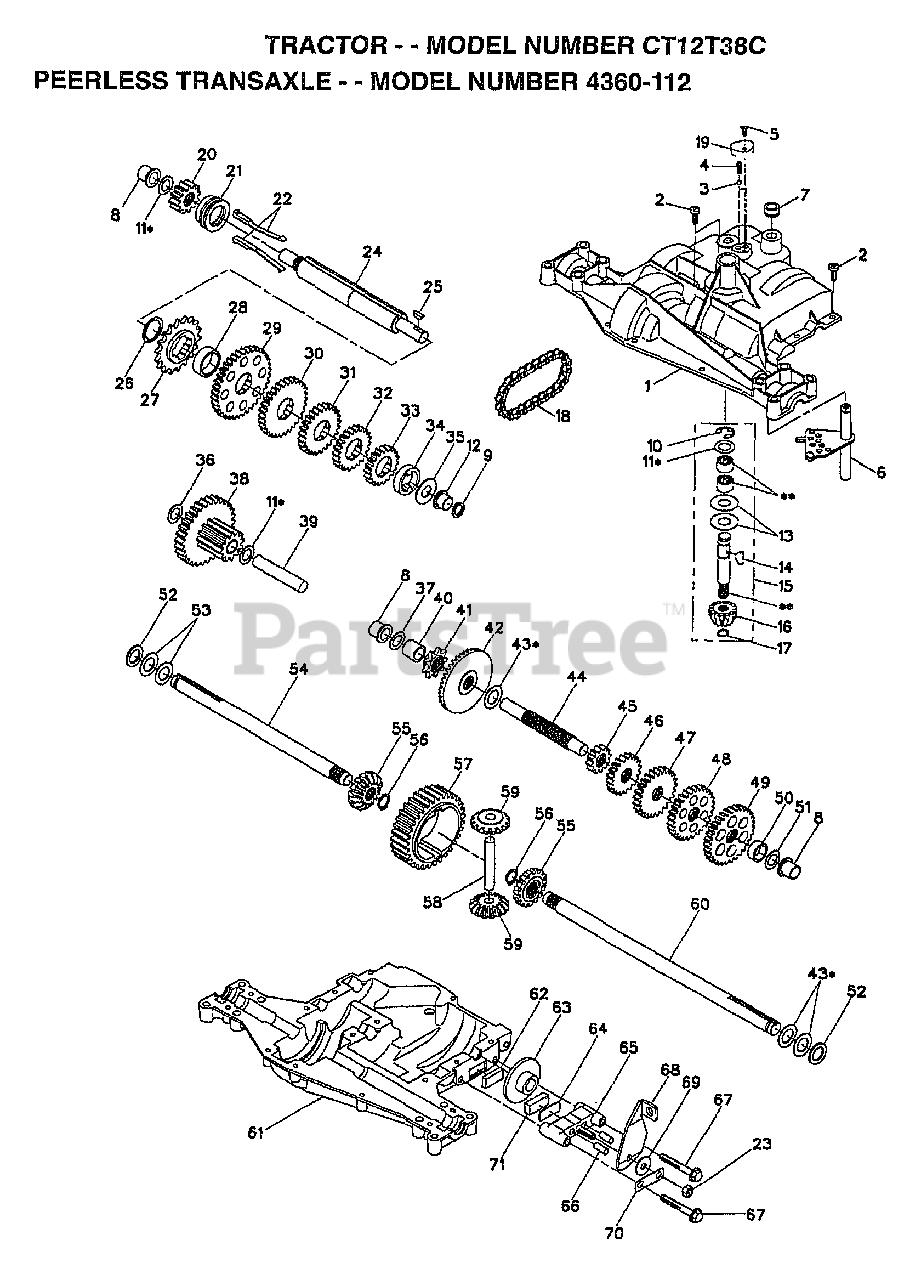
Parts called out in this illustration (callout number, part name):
1	HOUSING, UPPER
3	BALL, DETENT
4	SPRING, DETENT
5	SCREW, #10-24 X .482
6	SHIFTER ASSEMBLY
8	BEARING, FLANGE
10	RING, RETAINING
11	ASSY, KIT, SHIM .625 SHAFT
12	BEARING, FLANGE
13	WASHER, PLAIN .632 X 1.38 X .046
14	KEY, WOODRUFF, #9
15	ASSEMBLY, KIT, INPUT SHAFT
16	PINION, BEVEL, 14 TEETH
17	RING, RETAINING
18	CHAIN, 24 PITCHES
19	COVER, DETENT
20	GEAR, SPUR, 12T
21	COLLAR, CLUTCH
22	ASSEMBLY, KIT, CLUTCH KEYS
23	LOCKNUT 5/16-24
24	SHAFT, INTERMEDIATE
25	KEY, WOODRUFF, #61
26	RING, RETAINING
27	SPROCKET, 18 TEETH
29	GEAR, SPUR, 37 TEETH
30	GEAR, SPUR, 30 TEETH
31	GEAR, SPUR, 25 TEETH
32	GEAR, SPUR, 22 TEETH
33	GEAR, SPUR, 19 TEETH
35	WASHER, PLAIN .640 X 1.37 X .061
36	WASHER PLAIN
37	WASHER PLAIN
38	ASSY, GEAR COMB 12T & 30T
39	SHAFT, IDLER
40	SPACER .635 X .875 X .755
41	SPROCKET, 9 TEETH
42	GEAR, BEVEL, 42 TEETH
43	ASSY, KIT, SHIM .750 SHAFT
44	SHAFT, DRIVE
45	GEAR SPUR, 12 TEETH
46	GEAR, SPUR, 20 TEETH
47	GEAR, SPUR, 25 TEETH
48	GEAR, SPUR, 28 TEETH
49	GEAR, SPUR, 31 TEETH
51	WASHER, PLAIN .632 X 1.00 X .060
52	WASHER, NEOPRENE
53	WASHER, PLAIN .758 X 1.25 X .031
55	GEAR, MITER, 15 TEETH
56	RING, RETAINING
57	GEAR, SPUR, 32 TEETH
58	SHAFT, CROSS
59	GEAR, MITER, 15 TEETH
61	HOUSING, LOWER
62	PUCK, FRICTION
63	DISC, BRAKE
65	JAW, BRAKE
66	PIN, DOWEL
67	SCREW, 5/16-18 X 2.35
68	LEVER ACTUATING
69	WASHER, PLAIN .321 X 1.00 X .055
70	BRACKET, ANTI-ROTATION
71	PUCK, FRICTION
